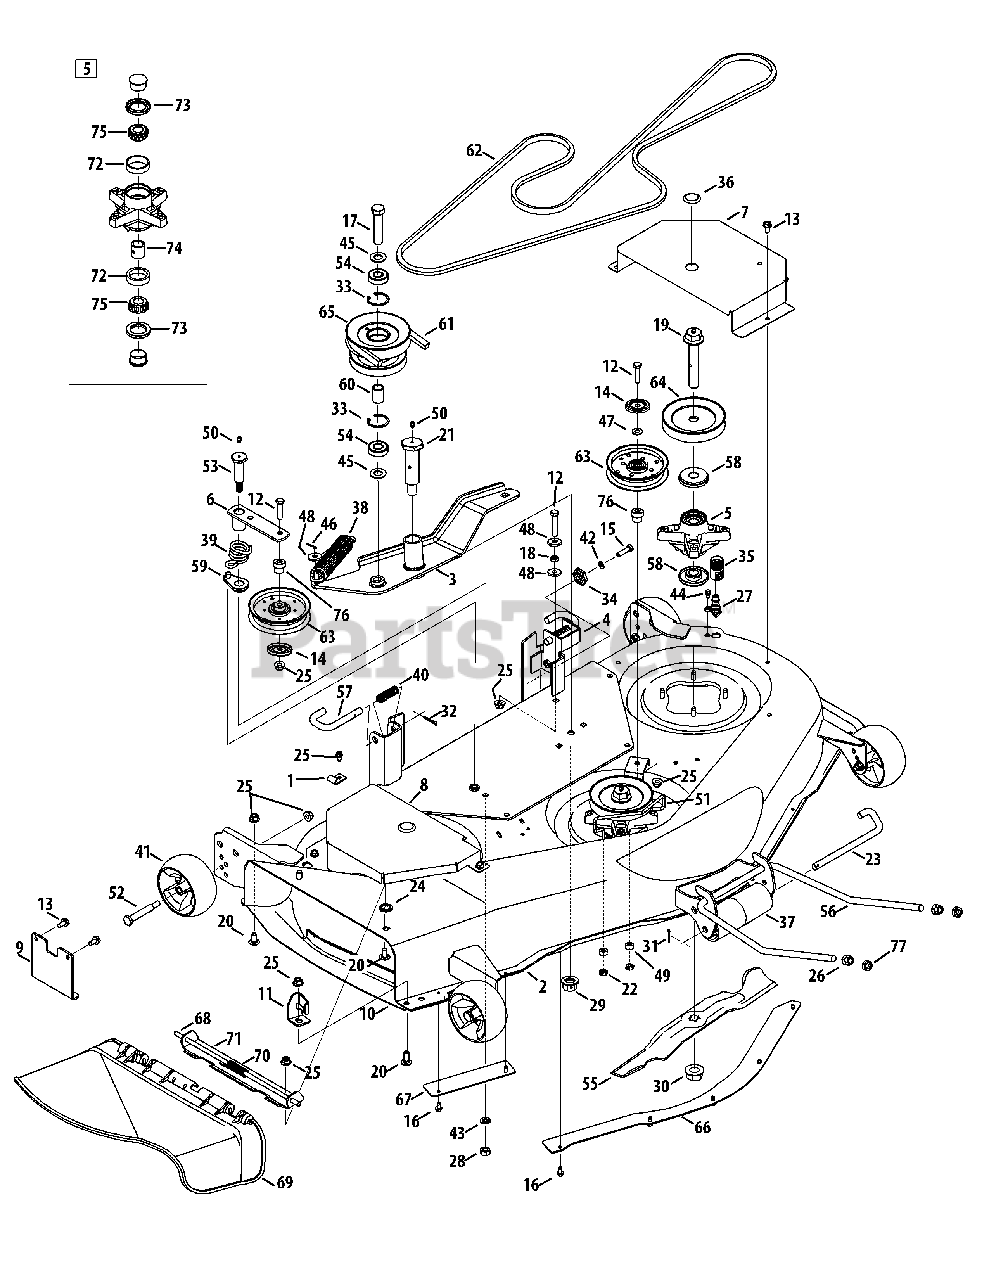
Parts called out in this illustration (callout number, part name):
1	Hook Retainer Bracket
4	Hanger Adjustment Bracket
5	Spindle Assembly
7	LH Spindle Shield
8	RH Spindle Shield
9	Up-Stop Bracket
12	Hex Screw, 3/8 x 16 x 1.75
13	Hex Washer Screw, 5/16-18 x .750
14	Pulley Cap
15	Hex Screw, 5/16-18 x 1.25
16	Hex Washer Screw, 1/4-20 x .500
17	SCREW 5/8-18X3.0 GR5
18	Jam Nut, 3/8 x 16
19	Spindle Bolt, 3/4-16 x 4.25
20	Carriage Bolt, 3/8-16 x 1.00
21	Shoulder Screw, 1.0 x 3.00
22	Hex Lock Nut, 1/4-20
23	Roller Pin, 1/2 x 7.31
24	Push Nut, 3/8
25	Flange Lock Nut, 3/8-16
26	Hex Nut, 1/2-13
27	Deck Wash Nozzle
28	Hex Nut, 7/16-14
29	Flange Lock Nut, 5/8-18
30	Flange Lock Nut, 3/4-16
31	Cotter Pin, 3/32 x 1.25
32	Cotter Pin, 5/32 x 1.25
33	Retainer Ring
34	Deck Adjustment Gear
35	Water Nozzle Adapter
36	Button Plug
37	Front Roller
38	Extension Spring, 1.25 x 6.9
39	Idler Torsion Spring, 1.10 x 1.3
40	Compression Spring, .66 x 1.8
41	Deck Wheel, 5.0
42	Lock Washer, 5/16
43	Lock Washer, 7/16
44	Shoulder Screw, 1/4-20 x 0.50
45	Flat Washer, .65 x 1.25 x .075
46	Cotter Pin, 3/32 x .750
47	Flat Washer, .406 x .812 x .051
48	Falt Washer, .385 x 1.00 x .135
49	Spacer, .256 x .500 x .240
50	Drive Lube Fitting, 3/16
51	Belt Drive Guard
52	Shoulder Screw, 1/2 x 2.50
53	Shoulder Screw, 7/16-14 x .687 x 2.443
54	Ball Bearing, .625 x 40 x 12
55	2-in1 Blade
56	Front Lift Rod
57	Mower Support Pin
58	DECK SPINDLE SPACER
59	Spring Retainer
60	Spacer, .88 x .635 x 1.25
62	Deck Belt
63	Idler Pulley
64	Spindle Pulley
65	Double Pulley
66	Center Skirt
68	Hinge Pin, .3175 x 14.06
69	Chute Deflector
70	Torsion Spring, .44 x 2.0
71	Chute Bracket
72	Bearing Cup, .750
74	Bearing Spacer, .78 x 1.0 x 1.0425
75	Cone Bearing, .750
76	Shoulder Spacer, Idler
77	Nut, Jam, 1/2-13
